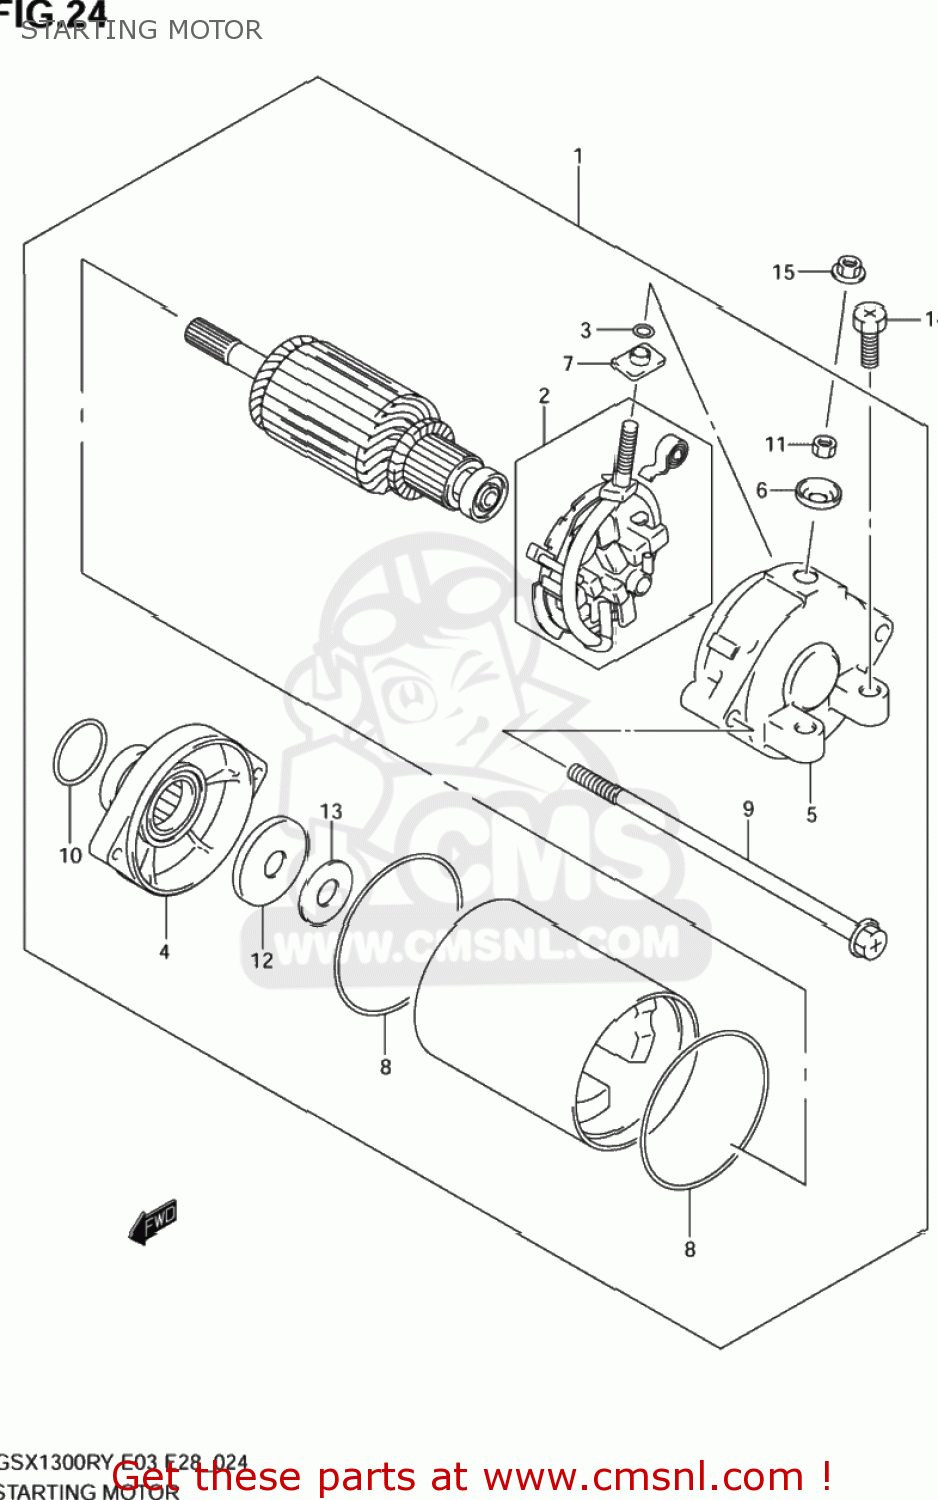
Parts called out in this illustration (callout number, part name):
1	MOTOR ASSY,STARTING
2	HOLDER SET,BRUSH
3	O RING
4	HOUSING ASSY,STARTER
5	FRAME,STARTER END
6	BUSHING
7	BUSHING
8	O RING
9	BOLT
10	O RING(D:3,ID:24.5)
11	NUT
12	WASHER
13	SHIM
14	SCREW (6X25)
15	NUT
